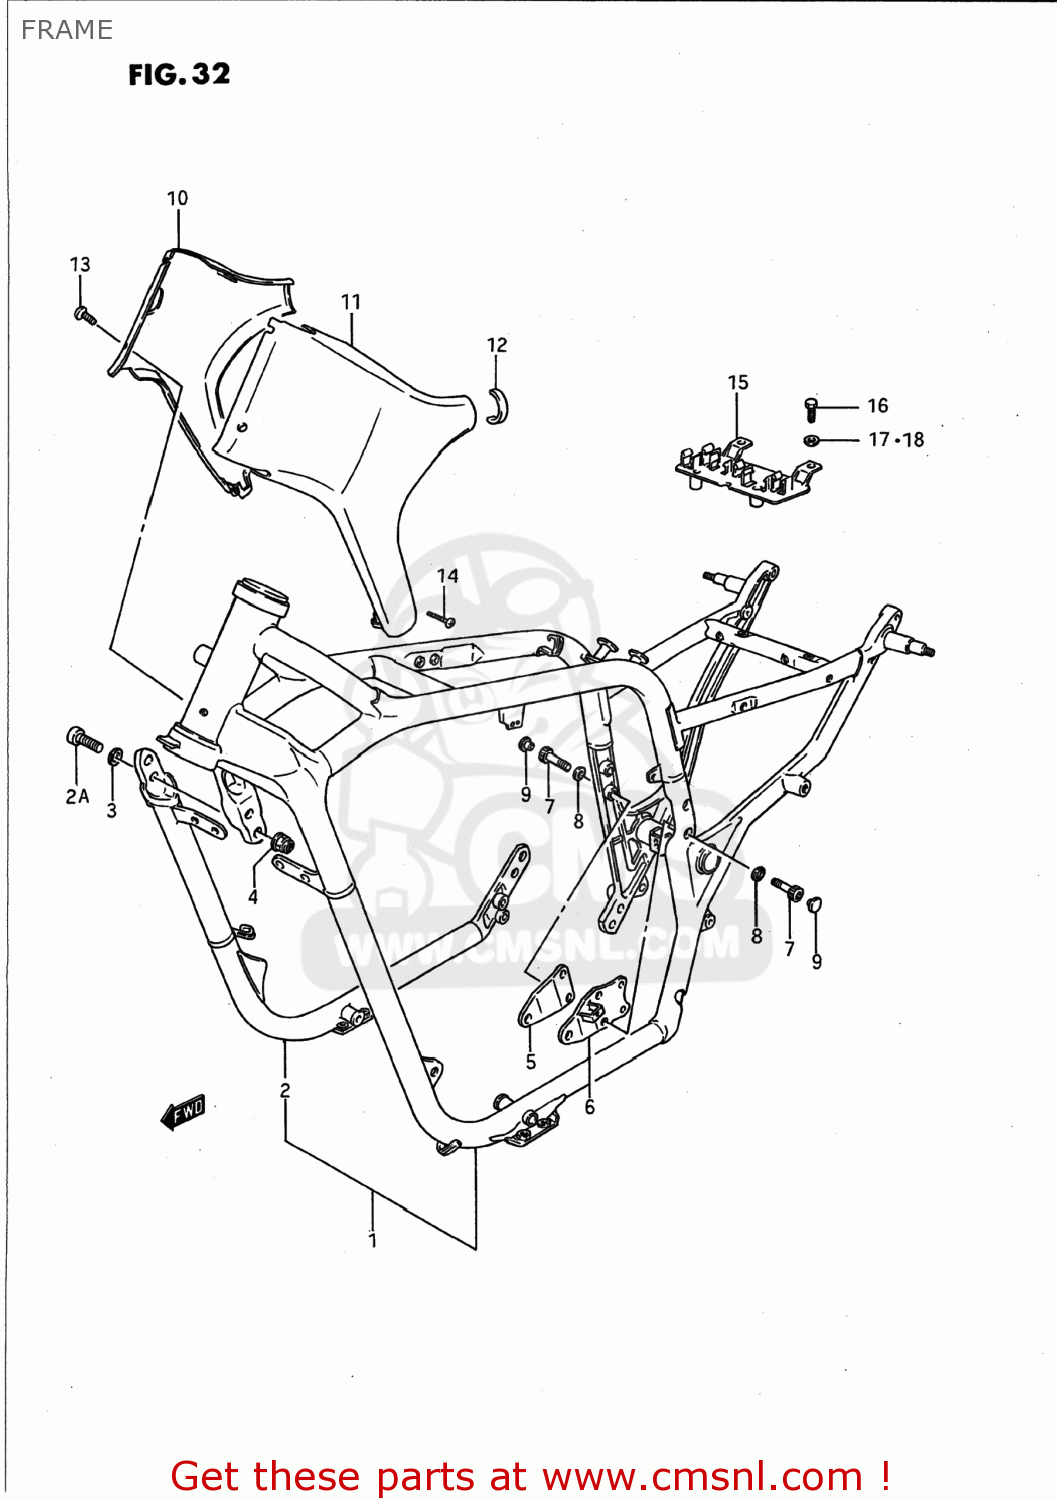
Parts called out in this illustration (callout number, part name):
1	FRAME
2	TUBE,FRAME
2A	BOLT(10X33)
3	WASHER
4	NUT 10MM
5	PLATE,ENGINE MOUNTING
6	PLATE,ENGINE MOUNTING
7	BOLT(8X32)
8	WASHER
9	CAP(OD:14.5)
10	COVER,FRAME HEAD,RIGHT
11	COVER,FRAME HEAD,LEFT
12	PROTECTOR,FRAME HEAD COVER
13	SCREW 5X10
14	SCREW
15	HOLDER,COUPLER
16	BOLT
17	WASHER
18	WASHER
